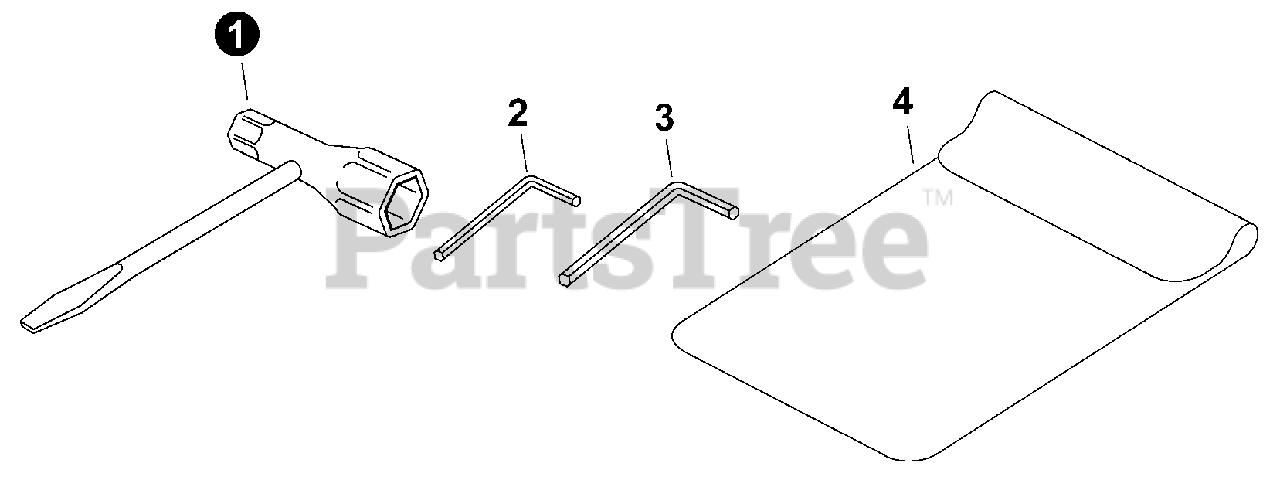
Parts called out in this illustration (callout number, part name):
1	T-WRENCH 13×19mm
2	WRENCH, ALLEN 4MM
3	WRENCH, ALLEN 5MM
4	BAG, TOOL
